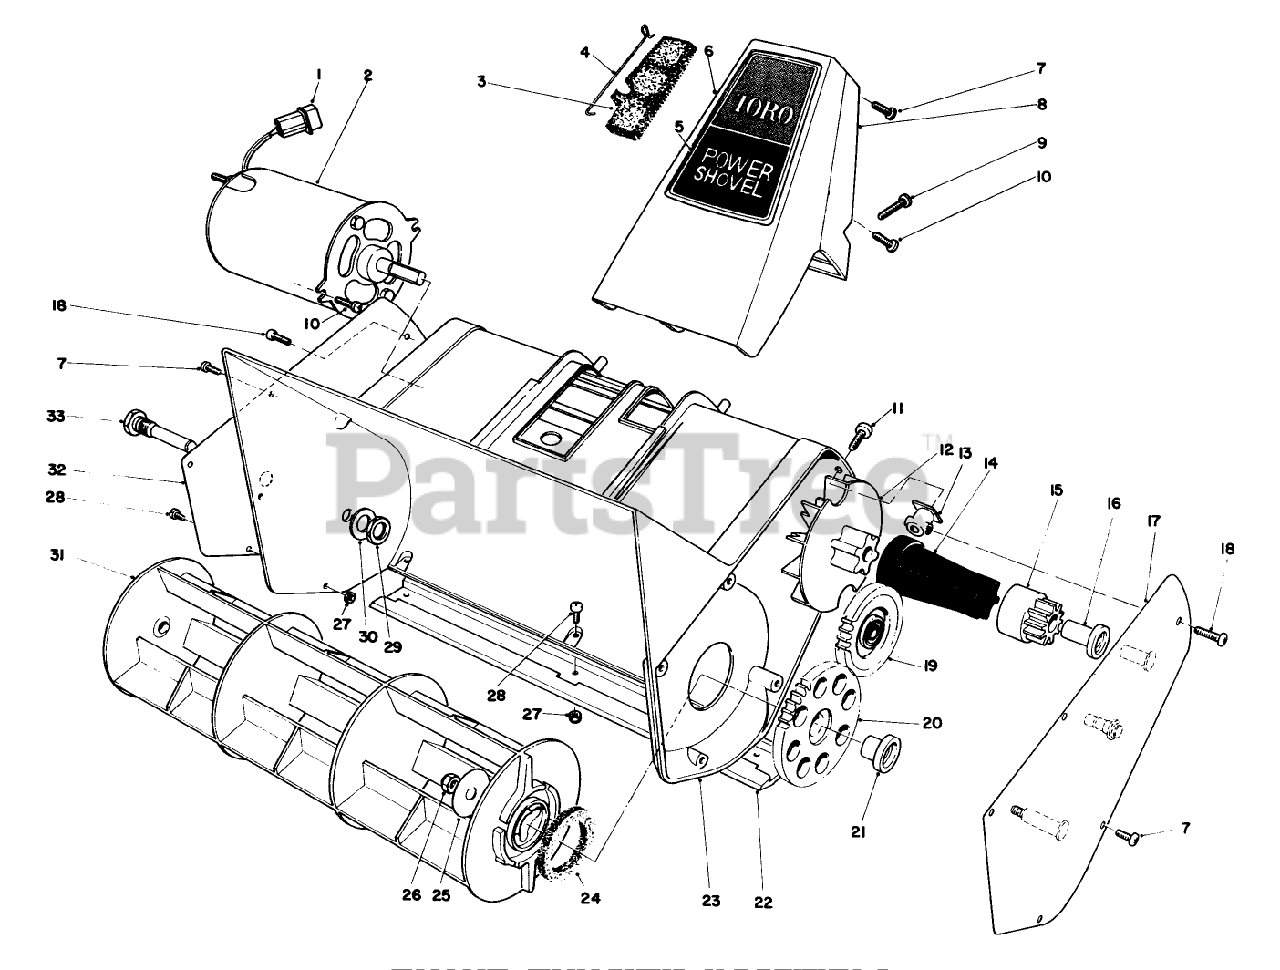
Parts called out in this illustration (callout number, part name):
3	FOAM FILTER
5	HANDLE SUPT DECAL
6	HANDLE SUPPORT, FRONT
7	SCREW-PPH
9	SCREW-PPH
10	SCREW-PPH
11	SCREW-PPH
12	FAN, POWER SHOVEL
13	MOUNTING BLOCK
14	DRIVE COUPLING
15	Blade Retainer
16	Latch-Door
24	FELT WASHER
25	ROTOR WASHER
26	NUT-LOCK, NI
27	NUT-LOCK
28	SCREW-PPH
29	NUT-HEX
30	WASHER-FLAT
31	ROTOR
32	RT. SIDE COVER (RAW)
33	ROTOR PIN
